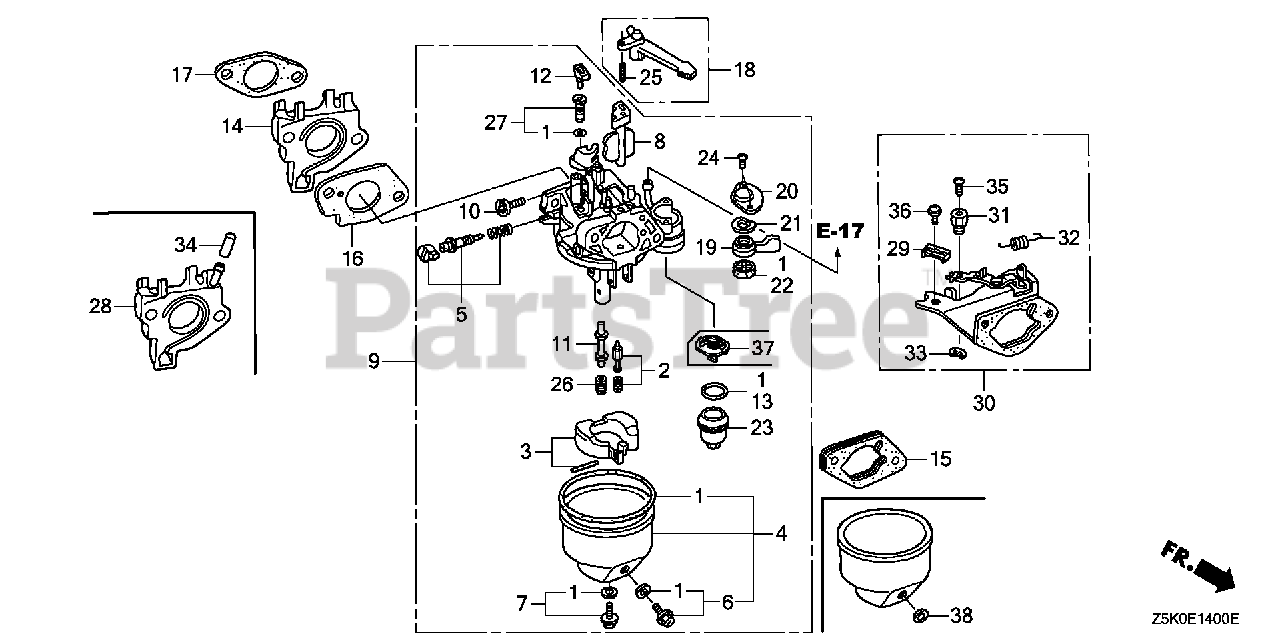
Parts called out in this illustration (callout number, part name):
1	GASKET SET (INCLUDES 16173-001-004)
2	VALVE SET, FLOAT
4	CHAMBER SET, FLOAT
5	SCREW SET, PILOT
6	SCREW SET, DRAIN
7	SCREW SET
9	CARBURETOR ASSY. (BE78B A)
10	SCREW, THROTTLE STOP
11	NOZZLE, MAIN
12	COLLAR, SETTING
13	GASKET, FUEL STRAINER CUP
14	INSULATOR, CARBURETOR
15	SPACER, CARBURETOR
16	GASKET, CARBURETOR
17	GASKET, INSULATOR
18	LEVER, CHOKE (STD)
19	LEVER, PETCOCK
20	PLATE, LEVER SETTING
21	SPRING, PETCOCK LEVER
22	GASKET, PETCOCK
23	CUP, FUEL STRAINER
24	SCREW, PAN (3X6)
25	PIN, SPRING (2X12)
26	JET, MAIN (#80)
26	JET, MAIN (#82)
26	JET, MAIN (#85)
27	JET SET, PILOT (#40) (CARBURETOR NO.)
